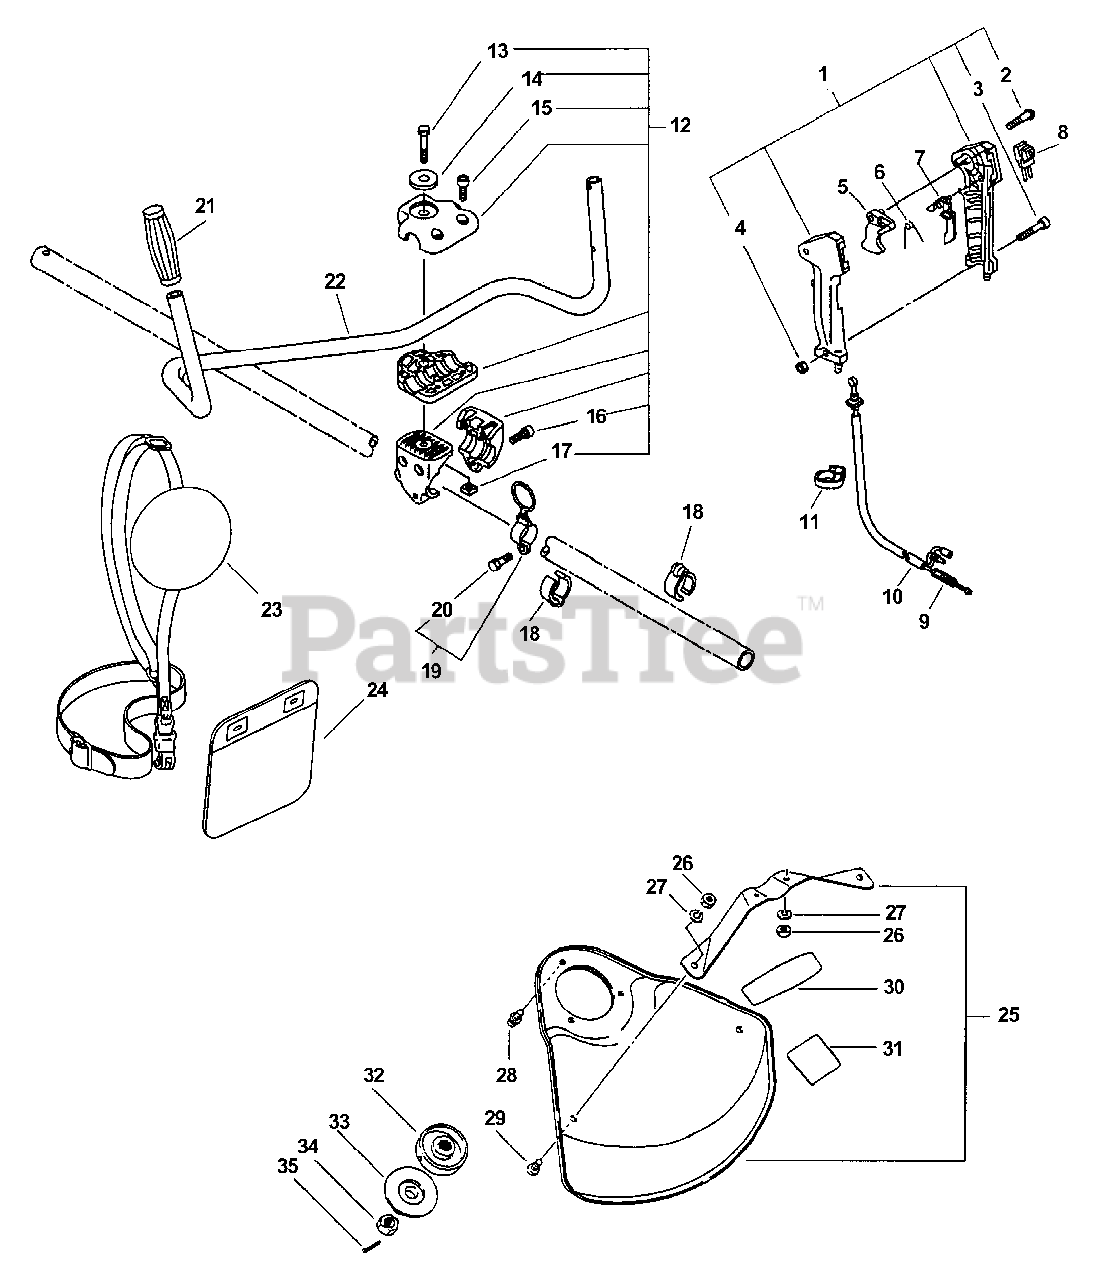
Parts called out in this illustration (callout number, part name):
1	CONTROL HANDLE KIT
2	SCREW 3×25
3	SCREW 5×30
4	NUT M5
5	TRIGGER, THROTTLE
6	SPRING, TORSION
7	LOCKOUT, THROTTLE
8	SWITCH, ON-OFF
9	CABLE, THROTTLE
10	TUBE, FLEXIBLE 7×790
12	BRACKET KIT, HANDLEBAR
13	BOLT 8×55
14	WASHER 8
15	BOLT 5×20
16	BOLT 5×30
17	NUT 8×1.25
18	CLIP, CABLE 25 MM
19	HANGER SET, HARNESS
20	BOLT 5×12
21	GRIP, HANDLE
22	HANDLEBAR
23	SHOULDER STRAP ASSY
24	PAD, HIP
25	SHIELD ASSY
26	NUT M5
27	WASHER, SPRING 5
28	SCREW 5×8
29	SCREW 5×10
30	LABEL, ECHO
31	LABEL, DANGER
32	PLATE, ADAPTER - UPPER
33	PLATE, ADAPTOR - LOWER
35	PIN, COTTER 2×22
